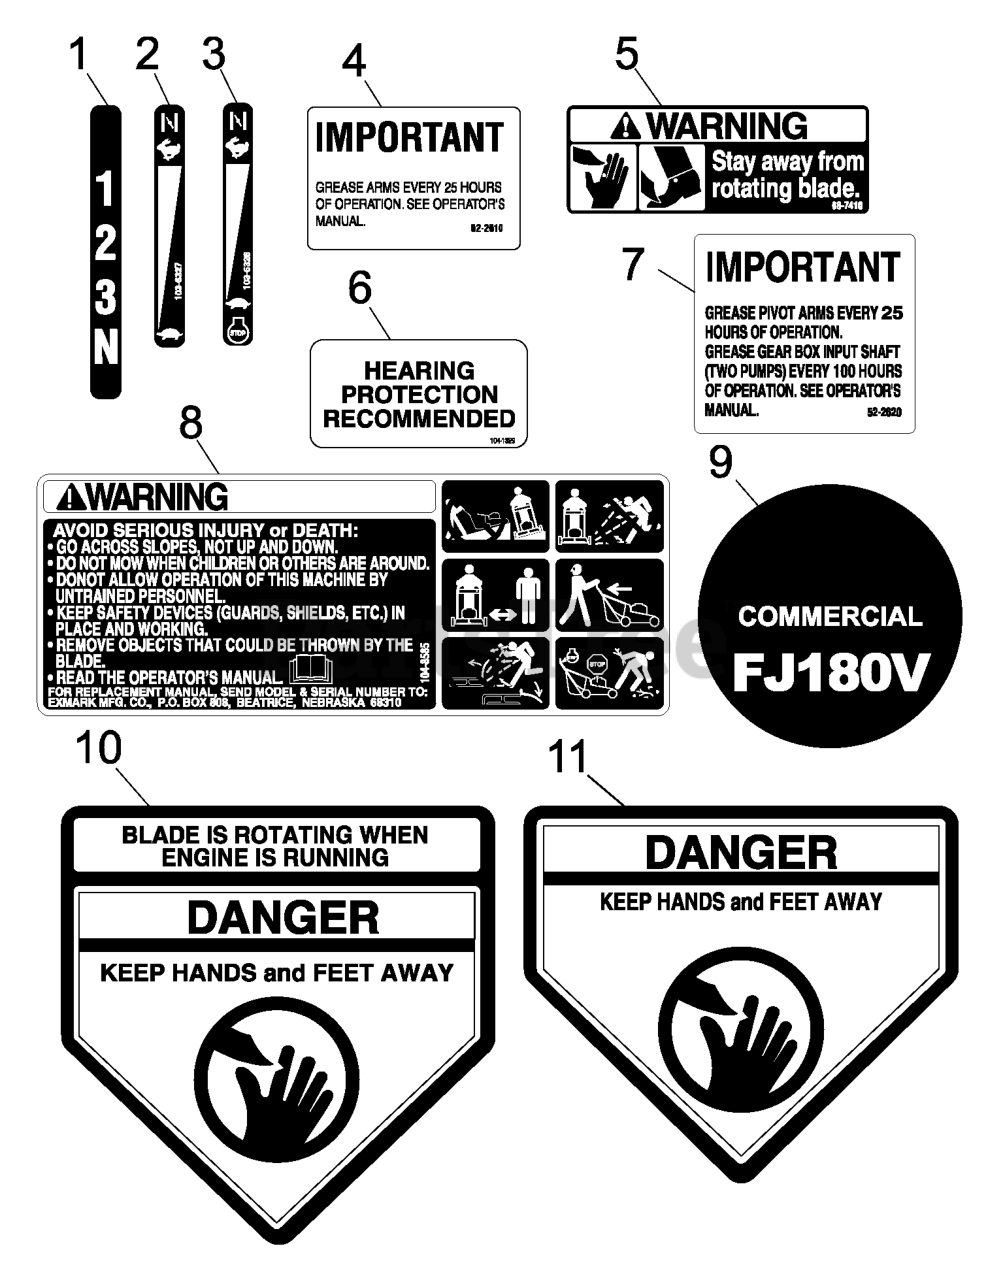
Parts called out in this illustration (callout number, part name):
1	DECAL,SHIFTER
2	DECAL,THROTTLE/CHOKE
3	DECAL-THROTTLE / CHOKE
4	LABEL-GREASE, HP
5	DECAL-BLADE
6	DECAL-PROTECTION, HEARING
7	Label, Grease
8	DECAL-WARNING
9	DECAL-RECOIL
10	DECAL-DANGER
11	DECAL-DANGER
